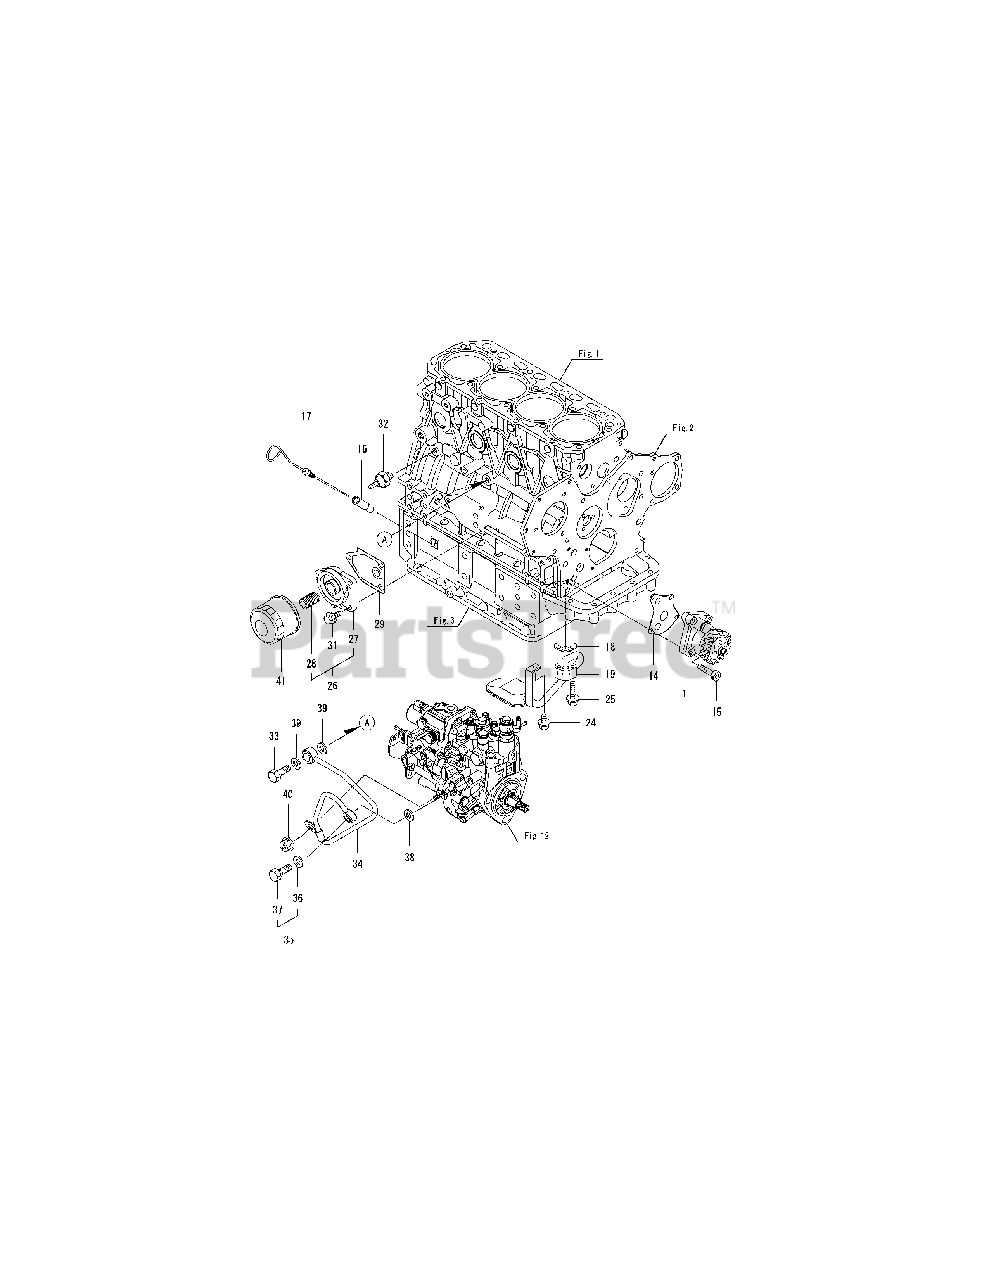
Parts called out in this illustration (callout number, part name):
1	PUMP ASSY, LUB.OIL
16	GUIDE, DIPSTICK
17	DIPSTICK, LUB.OIL
19	PIPE ASSY, OIL INLET
24	BOLT M 8X 12 PLATED
25	BOLT M 8X 35 PLATED
26	BRACKET ASSY, FILTER
27	BRACKET, FILTER
29	GASKET, BRACKET
31	BOLT M 8X 20 PLATED
32	SWITCH, OIL PRESSURE
33	BOLT, JOINT M10
34	PIPE ASSY, LUB.OIL
35	BOLT ASSY, JOINT
36	SEAL WASHER 8S
38	SEAL WASHER 8S
